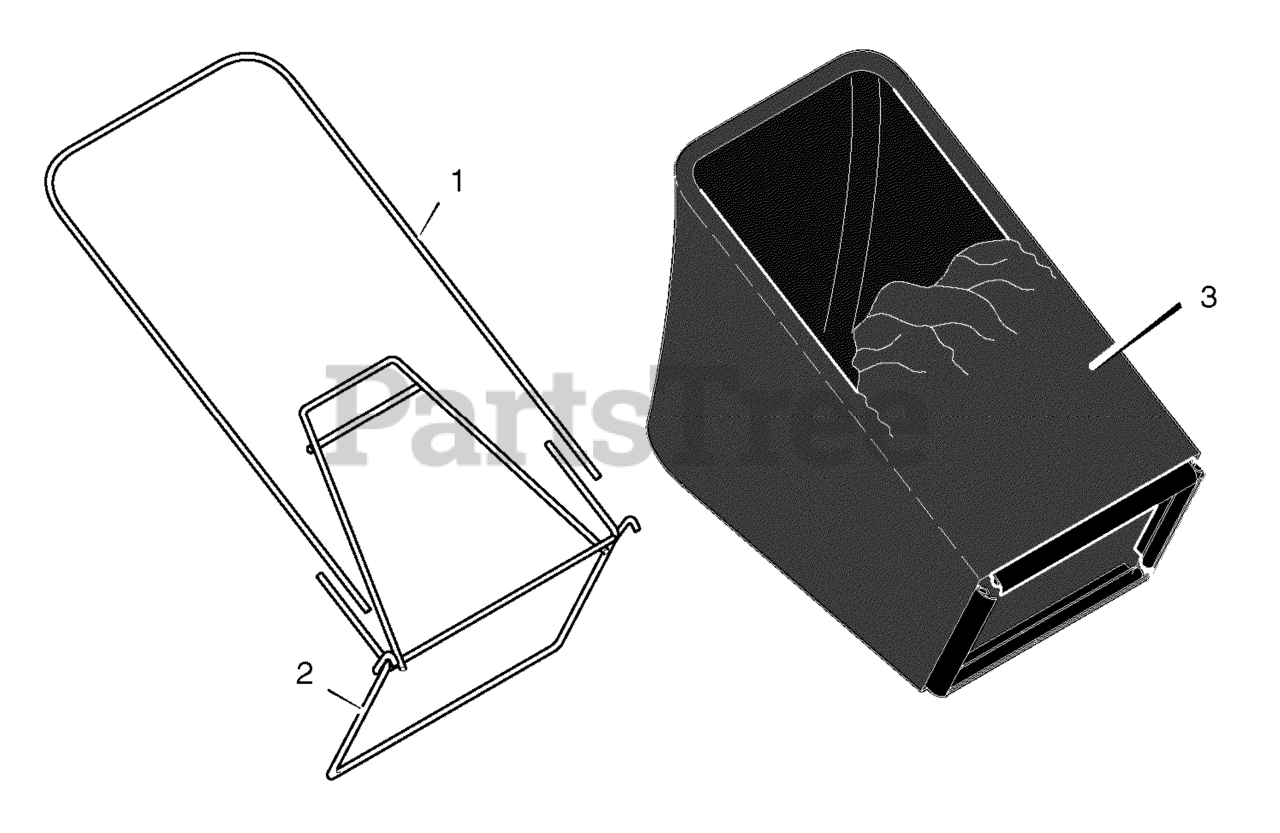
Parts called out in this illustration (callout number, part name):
1	Tube, Bag
2	Frame Assembly
3	Bag, Cloth
